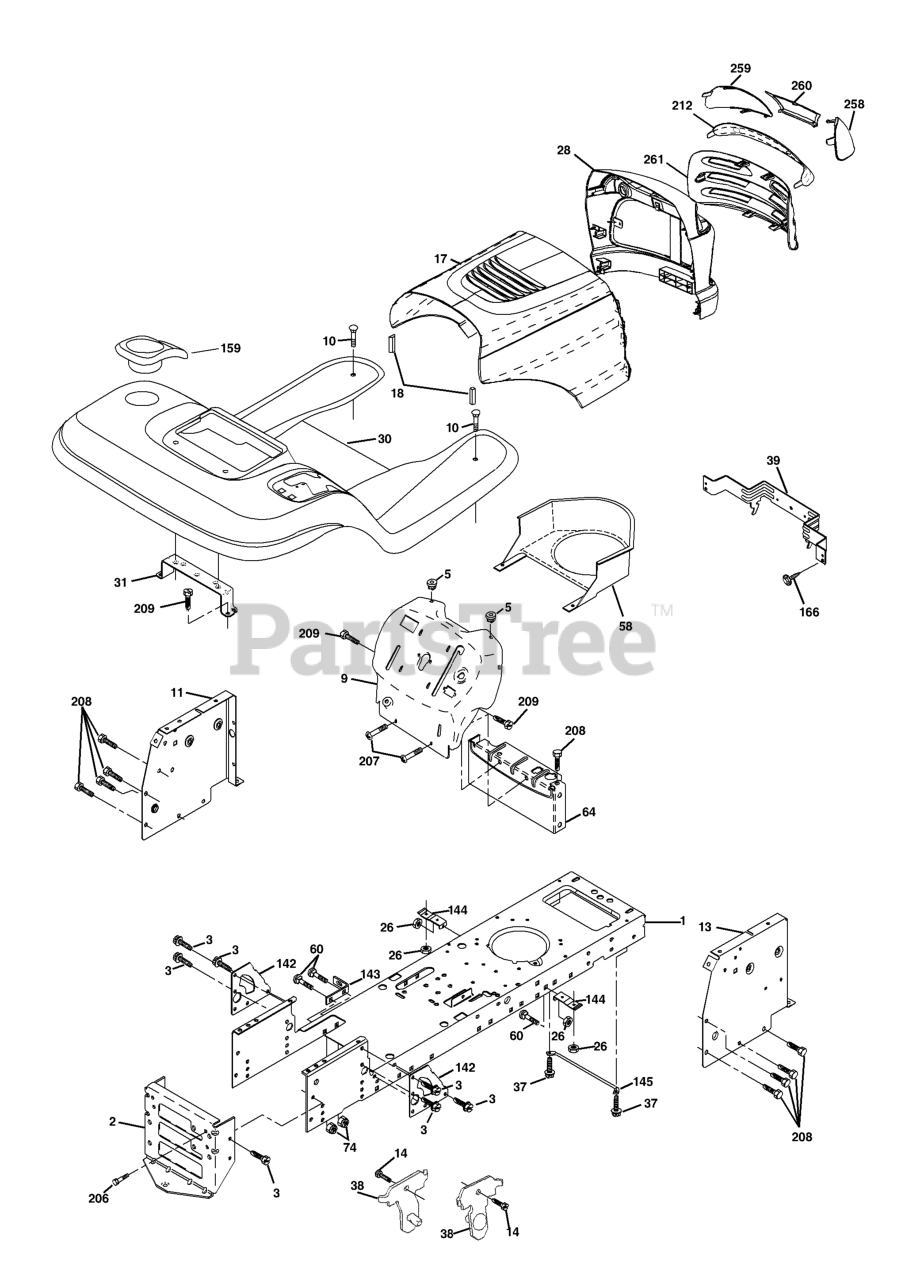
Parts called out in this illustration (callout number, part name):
1	CHASSIS STAMPING
2	DRAWBAR, 12GA
3	SCREW 3/8-16X3/4
5	BUMPER.RUBBER.HOOD
9	DASH
10	BOLT D
11	PANEL.DASH.LH.LTX
13	PANEL DASH RH
14	SCREW LT
17	HOOD
18	BUMPER.HOOD.LARGE.1.75"
26	NUT
28	GRILL/LEN.ASM.DL.HUSQ
30	FENDING
31	BRACKET.SUPPORT.FENDER
37	Screw Thdrol 6/16-18 x 1/2 TYT
38	BRACKET.ASM.PIVOT.MOWER.REAR
39	BRACKET PIVOT LASER
58	AIR DUCT P/L/LT
60	Bolt Rd Hd Sqnk 3/8-16 Unc x 3/4
64	DASH LOWER
142	PLATE REINFORCEMENT
143	BRACKET, SWAY BAR
144	BRKT, FOOT REST
145	ROD PIVOT CHASSIS/HOOD
159	CUPHOLDER
166	SCREW
206	SHOULDER BOLT 5/16-18TT
207	SCREW, 5/16-18 X 1/2
208	SCREW 3/8-16X1/2
209	SCREW, 3/8-16X3/4
212	INSERT.LENS.REFLECTIVE
258	LENS LH
259	LENS LH
260	COVER.LENS.HUSQ.( HAVE GRAY)
261	INSERT GRILLE
